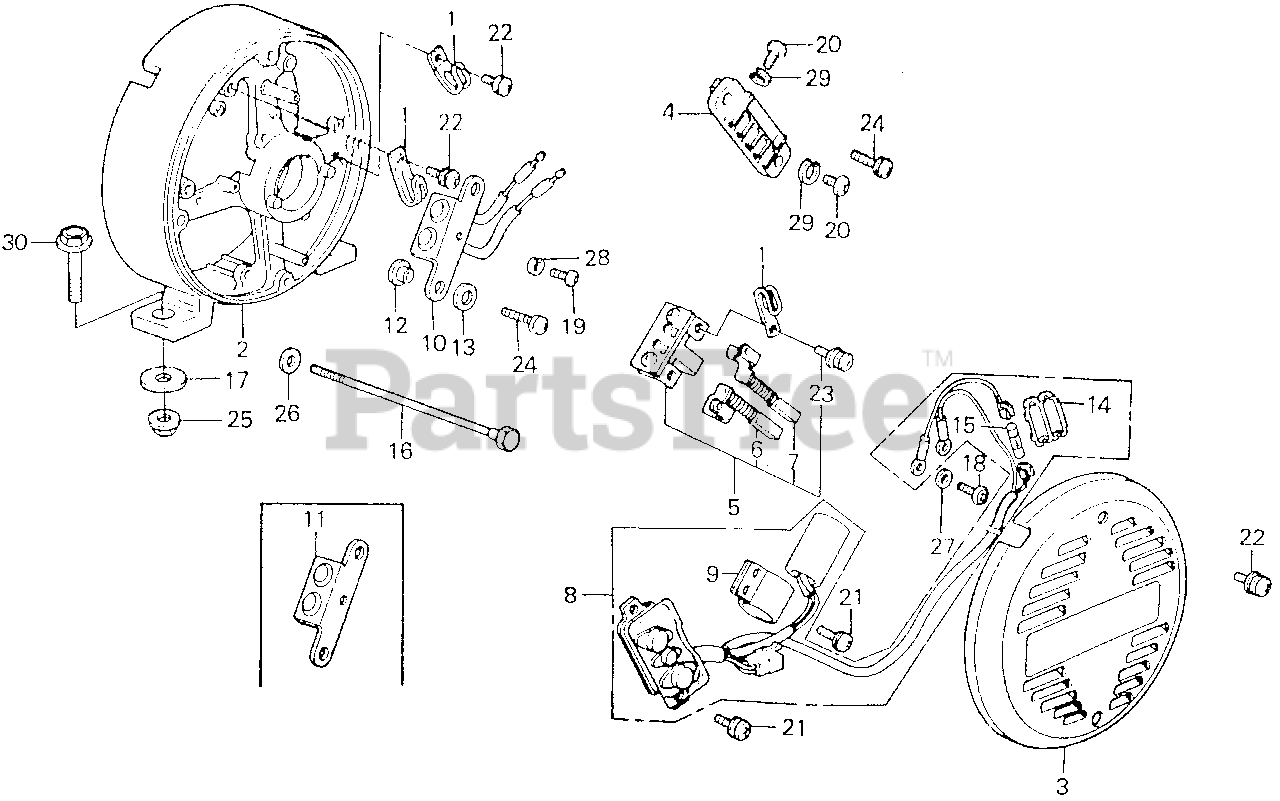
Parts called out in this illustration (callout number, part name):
1	CLAMP B, WIRE
2	HOUSING, RR. *NH31* (MCKINLEY WHITE) (NOT AVAILABLE)
3	COVER, ALTERNATOR END *R8* (BRIGHT RED) (NOT AVAILABLE)
4	TERMINAL, A.C. OUT
5	HOLDER ASSY., BRUSH
8	REGULATOR ASSY., AUTOMATIC VOLTAGE (NOT AVAILABLE)
9	HOLDER, CONDENSER
10	DIODE ASSY., D.C. (NOT AVAILABLE)
11	DIODE, D.C. (NOT AVAILABLE)
12	BUSH, INSULATING
13	WASHER, INSULATING
14	CASE, FUSE CONNECTOR
15	FUSE ASSY., SPARE
16	BOLT, HEX. (6X206)
17	WASHER, EX. MANIFOLD
18	SCREW, PAN (4X8)
19	SCREW, PAN (5X12)
20	SCREW, PAN (6X8)
21	SCREW-WASHER (5X12)
22	SCREW-WASHER (5X10)
23	SCREW-WASHER (5X14)
24	SCREW-WASHER (5X20)
25	NUT, FLANGE (10MM)
26	WASHER, PLAIN (6MM)
27	WASHER, SPRING (4MM)
28	WASHER, SPRING (5MM)
29	WASHER, SPRING (6MM)
30	BOLT, FLANGE (10X32)
